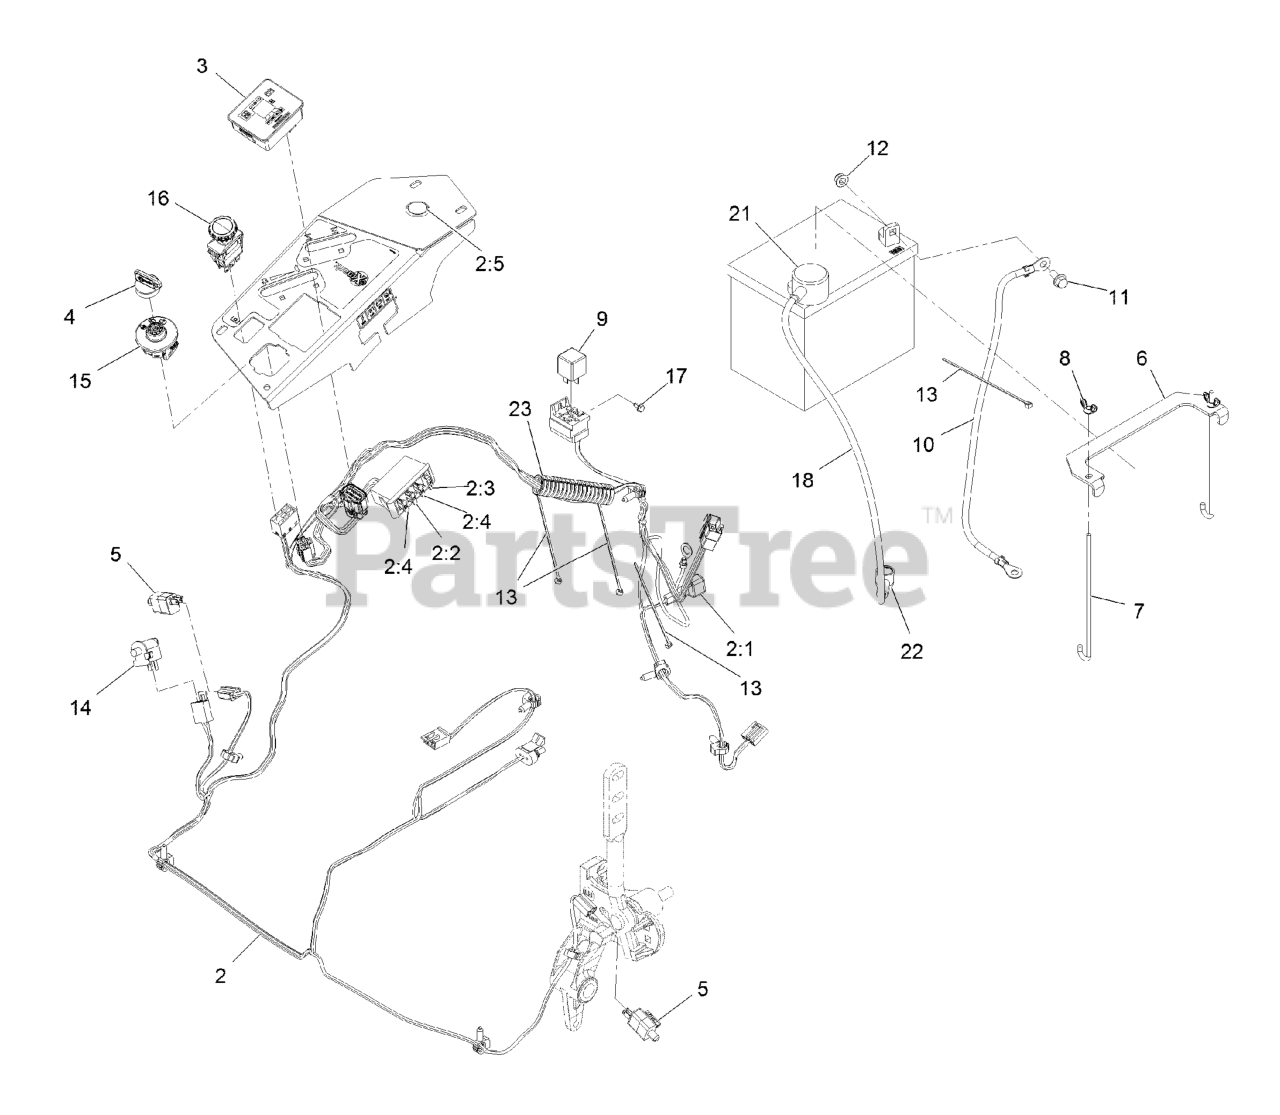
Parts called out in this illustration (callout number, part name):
2	HARNESS-WIRE, MAIN
2:2	FUSE-BLADE, 10 AMP
2:3	FUSE-BLADE, 15 AMP
2:4	FUSE-BLADE, 25 AMP
2:5	CAP-PLUG
3	FUEL/HOUR METER ASM
4	KEY-IGNITION
6	STRAP-TIE DOWN, BATTERY
7	BOLT-HOLDDOWN
8	WINGNUT
10	CABLE-BATTERY, NEGATIVE
11	SCREW-HHF
12	NUT-HF, NI
13	TIE-CABLE
14	SWITCH-BAIL
16	SWITCH-PTO, 10 AMP
17	SCREW-HWH
18	CABLE-BATTERY, POSITIVE
19	WASHER-FLAT
20	TIE-PLASTIC
27	INSULATOR-BATTERY
28	INSULATOR-SOLENOID
